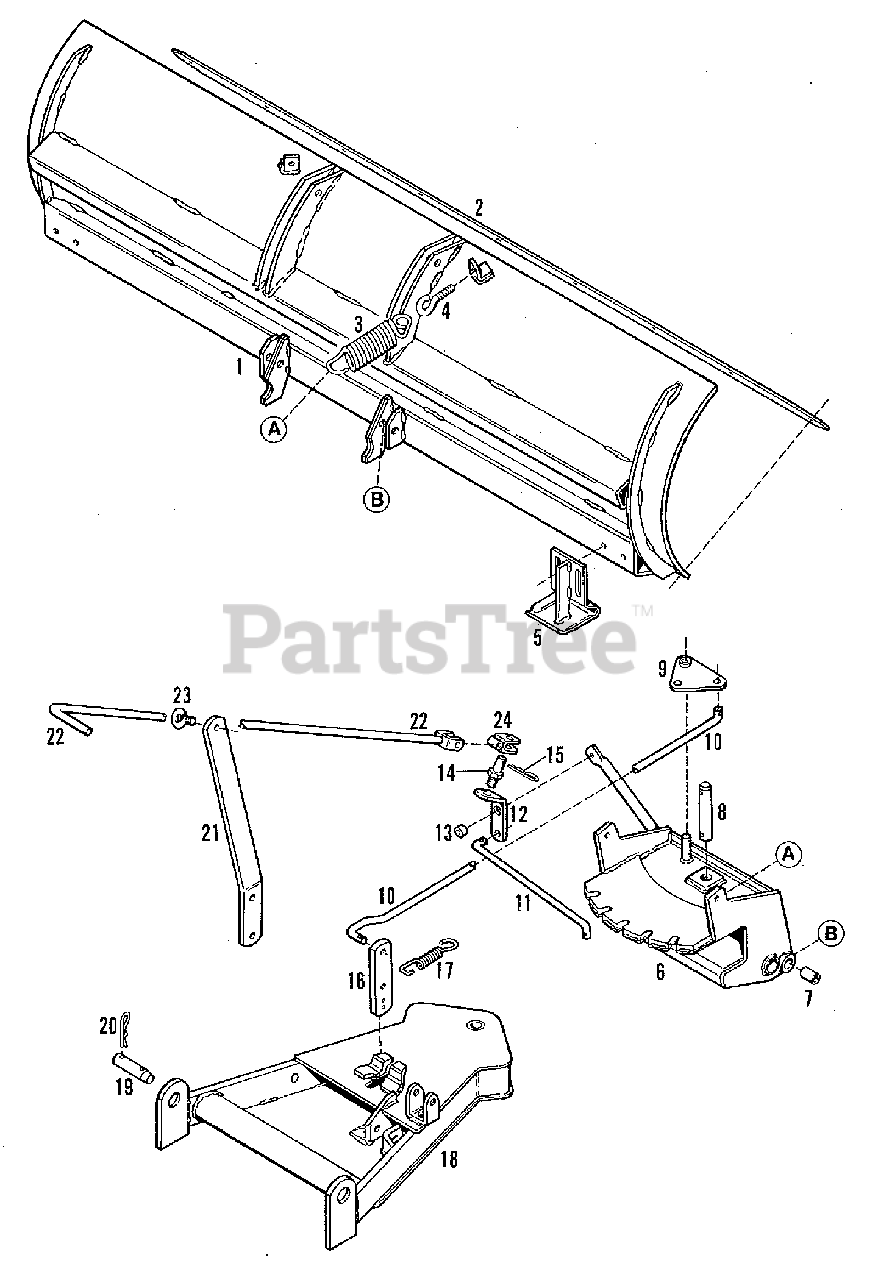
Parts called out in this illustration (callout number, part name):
1	BLADE ASSEMBLY (60")
1	CAPSCREW, 1/2NC x 2-1/4
1	NUT, Lock, 1/2NC
2	PLATE, Wear
2	BOLT, Carriage, 3/8NC x 1
2	LOCKWASHER, 3/8
3	SPRING, Tension
4	NUT, 5/16NC
5	SHOE ASSEMBLY
5	CAPSCREW, 3/8NC x 3/4
5	WASHER, Plain, 7/16 x 1 x 14 GA.
5	LOCKWASHER, 3/8
6	FRAME ASSEMBLY, Pivot
6	PIN, Cotter, 1/8 x 1
8	PIN, Cotter, 3/16 x 2
9	PLATE ASSEMBLY, Pivot
9	PIN, Cotter, 3/16 x 2
10	PLATE ASSEMBLY, Pivot
10	PIN, Cotter, 3/32 x 3/4
11	PIN, Cotter, 3/32 x 3/4
12	CAPSCREW, 5/16NC x 1
12	WASHER, Plain, 3/8 x 7/8 x 16 GA
12	LOCKWASHER, 5/16
12	NUT, 5/16NC
14	STUD, Pivot
14	LOCKWASHER, 5/16
14	NUT, 5/16NC
15	CLIP, Hairpin (Pkg. Of 8)
16	PIN, Spring, 7/32 x 1
18	FRAME ASSEMBLY
20	CLIP, Hairpin (Pkg. Of 4)
21	ARM, Support
21	CAPSCREW, M12 x 1.5 x 35MM
21	LOCKWASHER, 12MM
22	HANDLE ASSEMBLY
22	CAPSCREW, 5/16NC x 1-1/2
22	NUT, Lock, 5/16NC
23	LOCKWASHER, 1/4
24	FORK ASSEMBLY
